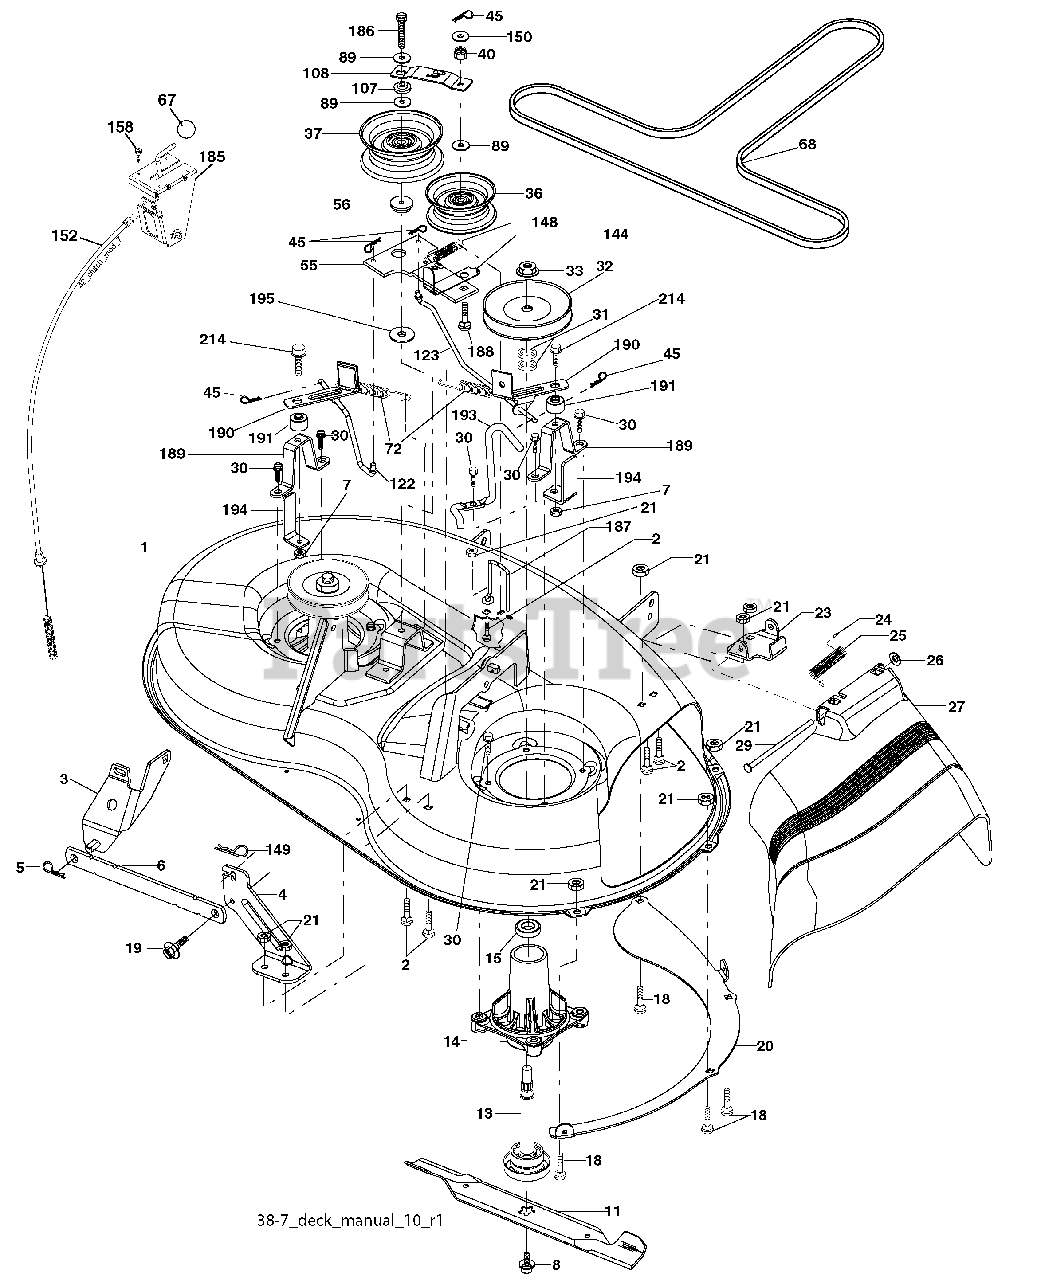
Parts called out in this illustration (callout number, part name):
1	Mower Housing Assembly
2	Bolt Carriage 5/16-18 x 3/4
3	Bracket Asm Fr. Sway Bar
4	Bracket Deck Sway Bar 38"/42"
5	Retainer Spring
6	Bar Sway Deck
7	Nut Lock 5/16-18 UNC
8	Bolt 3/8-24 x 1.25 Gr. 8
11	Blade Mower 38" High PERF
11	Blade 38" 3 in 1 Premium
13	Shaft Assembly, Mandrel, Vented
14	Housing, Mandrel, Vented
15	Bearing, Ball, Mandrel
18	Blade Rdhd Sqnk 5/16-18 x 5/8
19	Bolt, Shoulder
20	Baffle Vortex Front
21	Nut
23	Bracket, Mower Deflector
24	Cap, Sleeve
25	Spring, Torsion, Deflector
26	Nut, Push
27	Shield, Deflector
29	Rod, Hinge
30	Screw Thdrol.
31	Washer, Spacer
32	Pulley, Mandrel
33	Nut, Toplock
36	Pulley, Idler, Flat
37	Pulley, Idler Flat
40	Nut, Crownlock 3/8-16 unc
45	Retainer
55	Idler Arm Assembly
56	Spacer, Retainer
67	Knob
68	V-Belt
72	Spring Brake Return
89	Washer 13/32 x 13/16 x 11 Ga.
107	Spacer Retainer
108	Stiffener, Idler Arm
122	Rod, Brake LH
123	Rod, Brake RH
144	Keeper Belt Idler Tension
148	Spring Return Idler
149	Retainer Spring Yellow
150	Washer 9/32 x 3/4 x 10 Ga.
152	Clutch Cable 38"
158	Screw Hex Thd Cut 1/4-20 x 1/2
185	Head Asm Cable Clutch
186	Screw Hex Wsh Thdrol 3/8-16 x 2-3/4
187	Keeper Belt M Shape
188	Bolt Carriage Idler
189	Brake Stand
190	Brake Arm
191	Brake Spacer
193	Keeper Belt Rh Mandrel
194	Brake Guard
195	Washer 13/32 x 2 x 10 Ga.
214	Bolt/Washer Asm. 5/16-18
214	Brake Assembly
214	Mandrel Assembly
214	Replacement Mower, Complete
